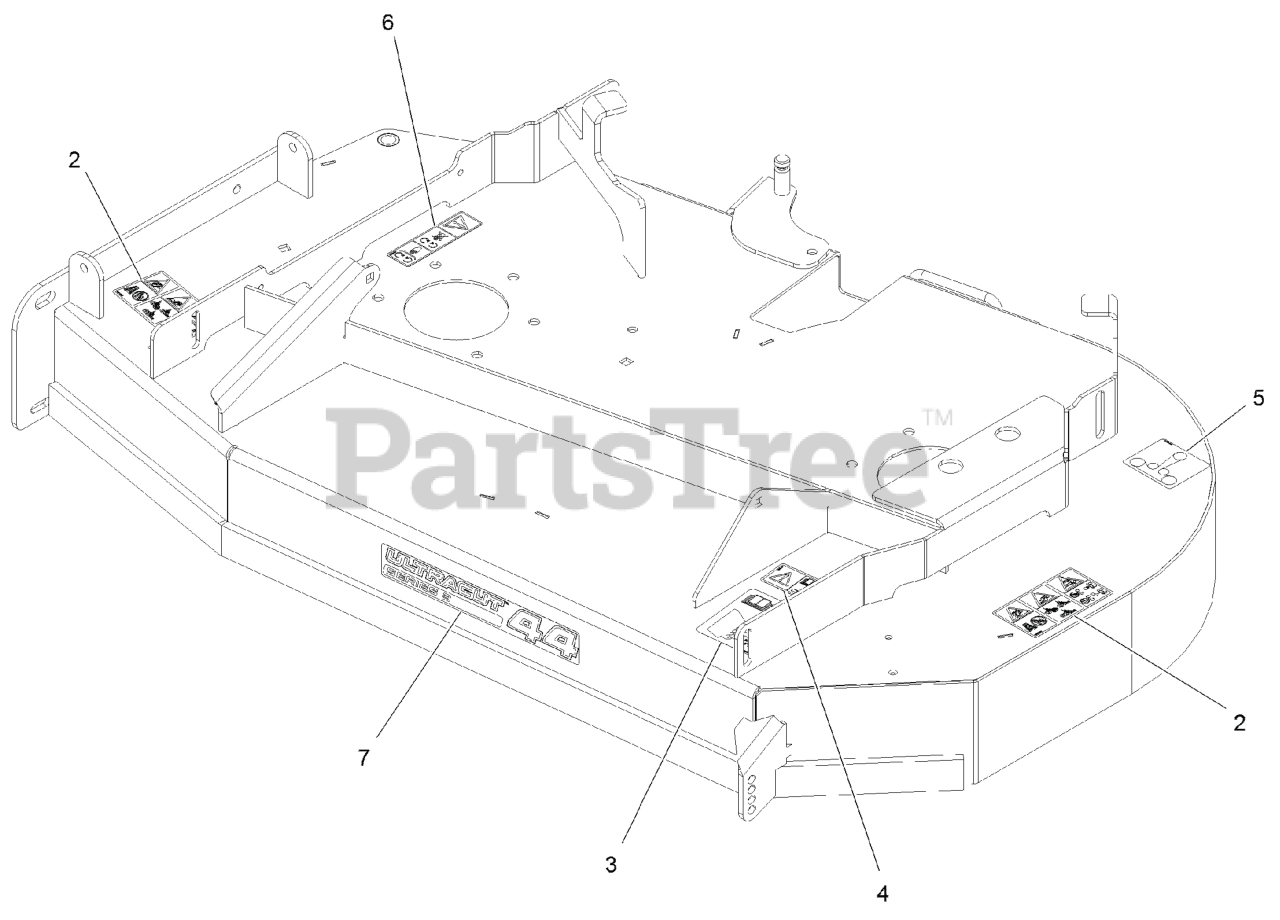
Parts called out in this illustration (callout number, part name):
2	DECAL-DANGER THROWN OBJECTS
3	DECAL-ROLLER, ANTI-SCALP
4	DECAL-TORQUE, BOLT
5	DECAL-ROUTING, BELT
6	DECAL-COVER, MISSING
7	DECAL-ULTRACUT 44 SERIES 3
